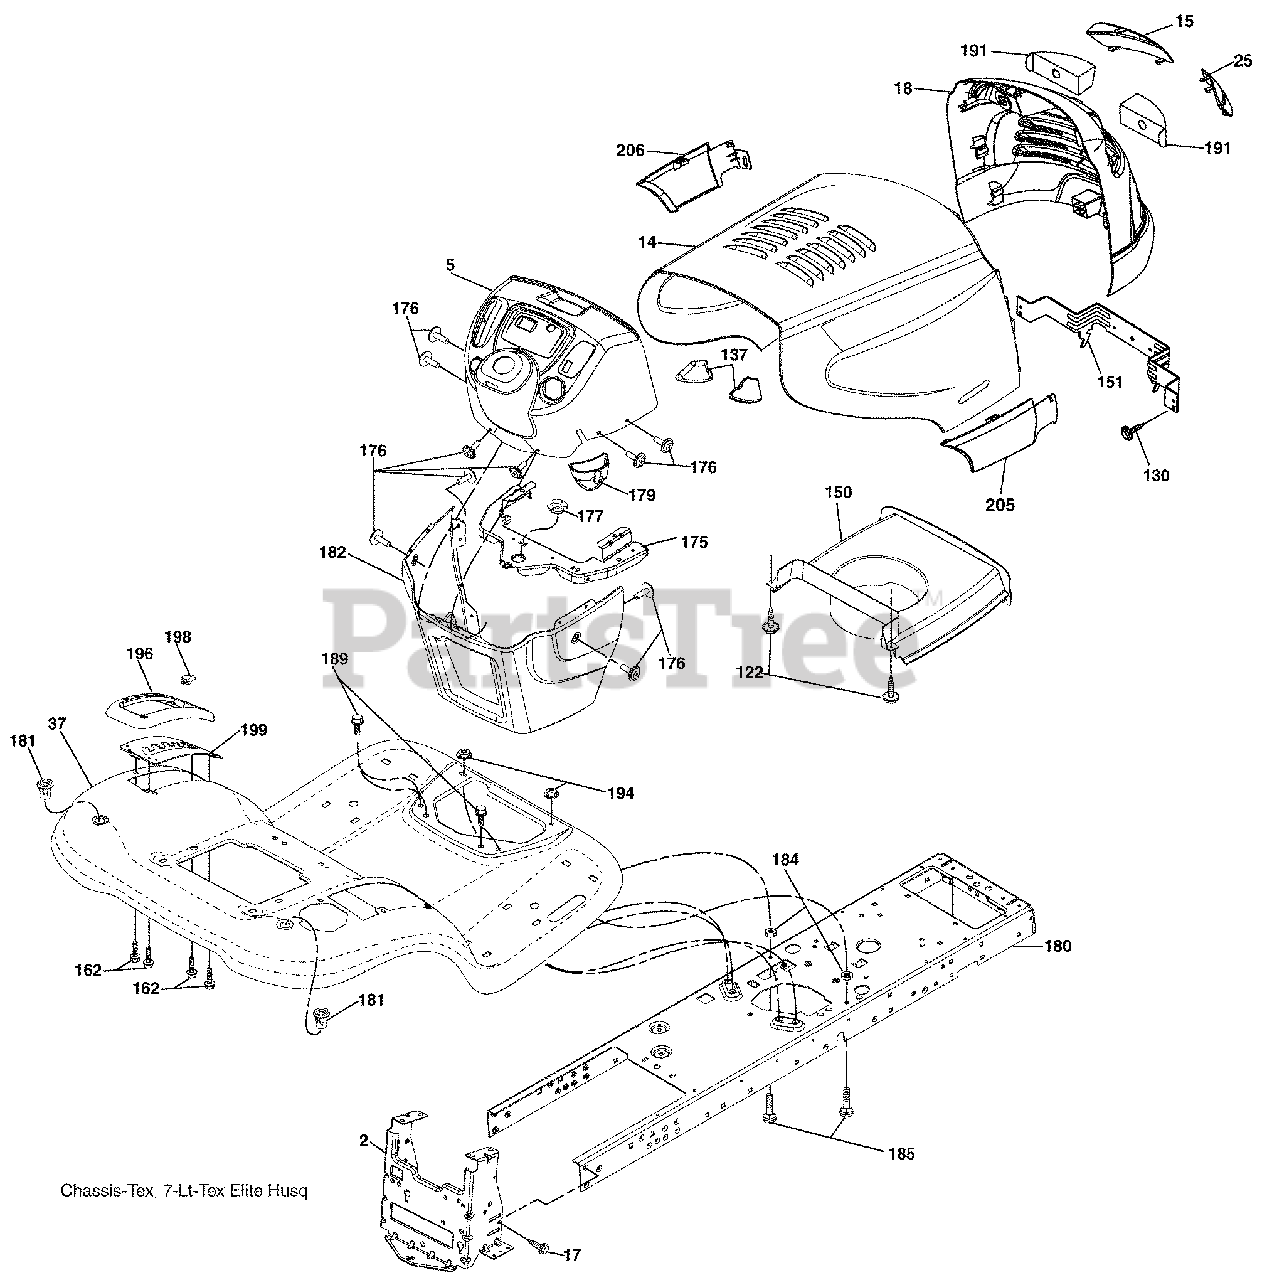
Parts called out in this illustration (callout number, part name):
14	Hood
15	Lens LH
17	Screw 3/8-16 x .75
18	Grille/Lens Asm.
25	Lens RH
37	Fender
122	Screw 10-32 x 5/8
130	Screw 10 x 3/4 Single Lead-Hex
137	Bumper Hood
138	Cupholder
151	Bracket Pivot
175	Crossmember
176	Screw 10-24 x 5/8
177	Bushing Steering
179	Plug Cruise Control
180	Chassis
181	Bushing Mtg. Fender Crgo
182	Dash Lower
184	Spacer Fender
185	Bolt Carraige 5/16-18 x 1-1/4 Gr. 5
189	Screw 5/16-18 x 3/4
191	Insert Lens
194	Nut Lock Hex Flange 5/16-18
196	Console Asm. Deck Lift
197	Rod Pivot Chassis/Hood
198	Indicator Deck Lift
199	Plate Deck Lift
205	Skirt Side RH
206	Skirt Side LH
